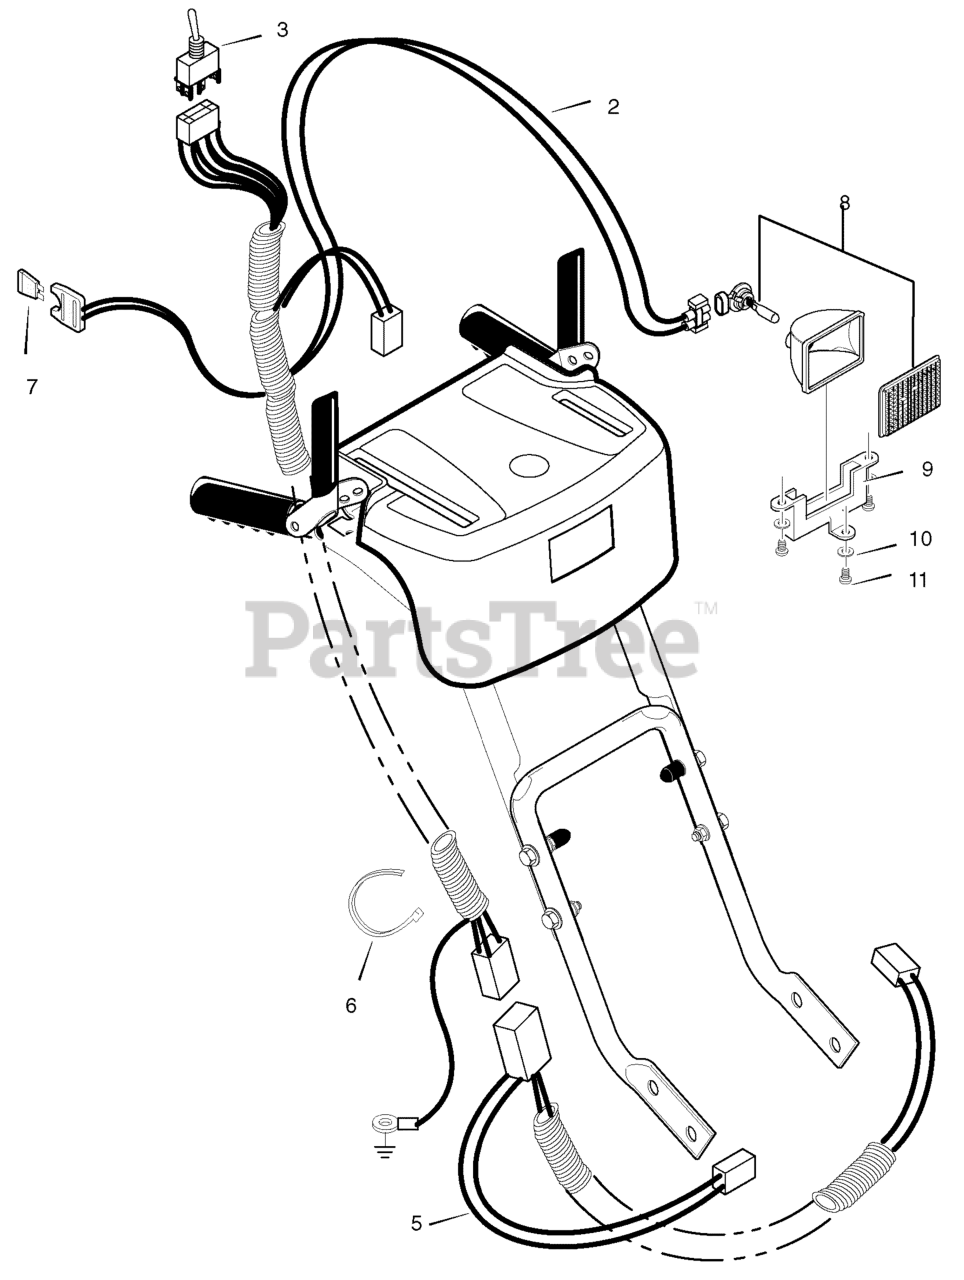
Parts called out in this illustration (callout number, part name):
2	WIRE, HARNESS
3	SWITCH, CHUTE ROTATION
5	WIRE HARNESS, LOWER
6	TIE, CABLE
7	FUSE, 7.5 AMP AUTOMOTIVE
8	HEADLIGHT ASSEMBLY *
9	BRACKET, LIGHT
10	WASHER, FLAT
11	SCREW #8 X .50
